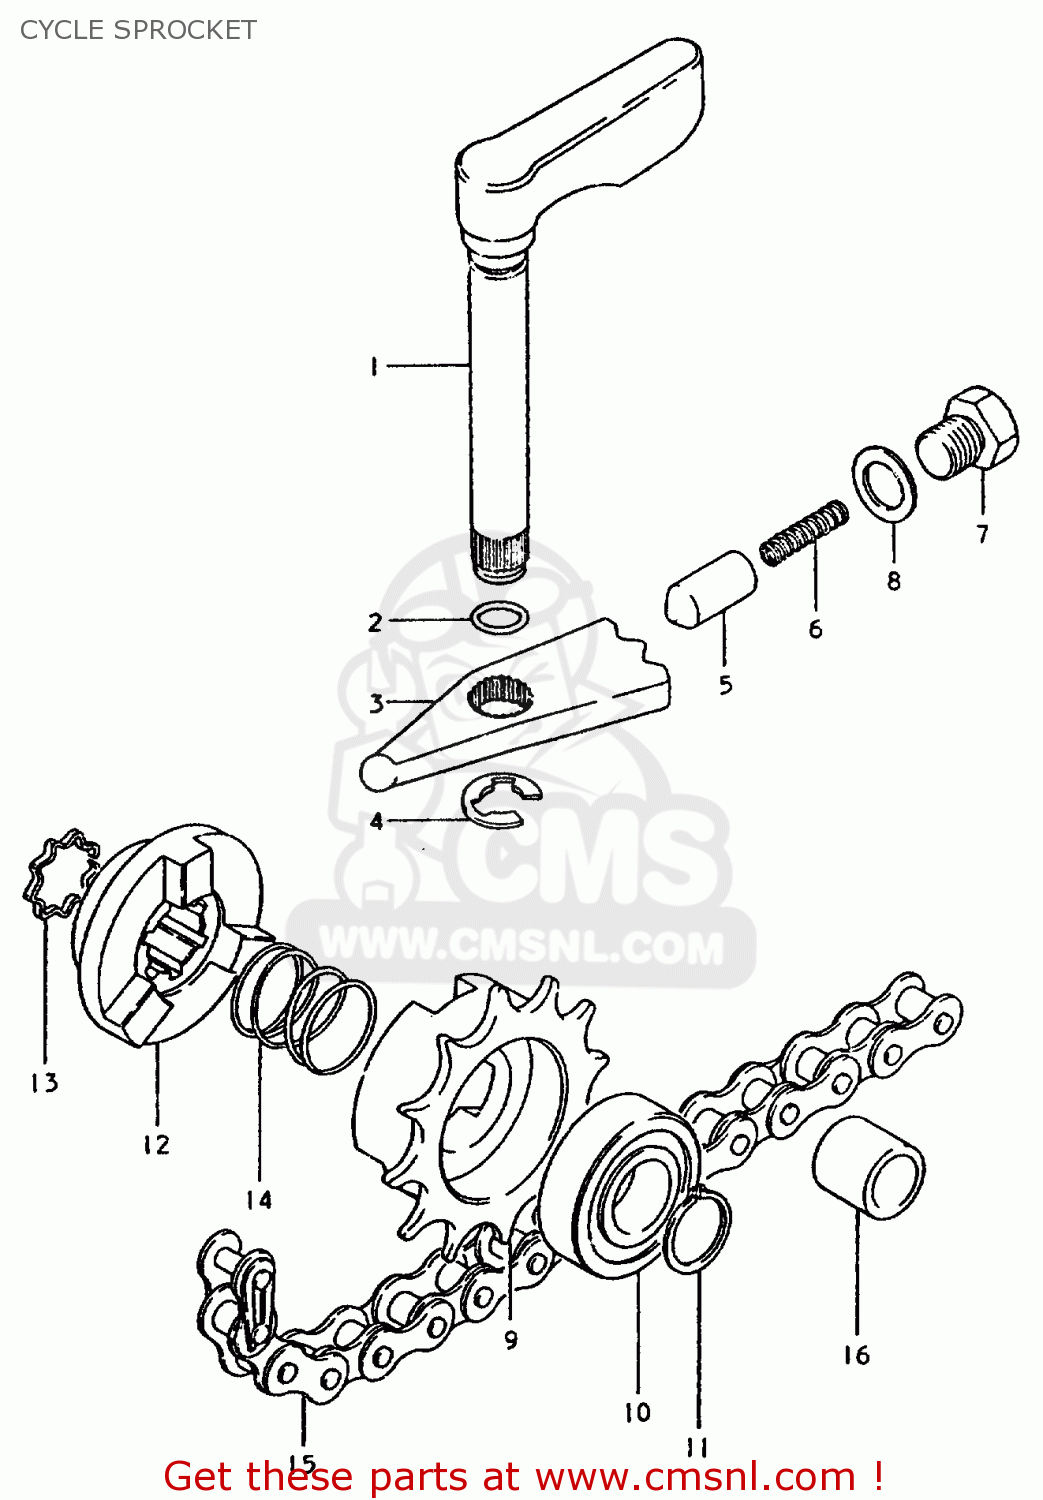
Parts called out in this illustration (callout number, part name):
1	LEVER, SPROCKET SHIFTING
2	O RING(D:1.3,ID:7.6)
3	ARM, SPROCKET SHIFTING
4	E RING
5	STOPPER
6	SPRING
7	BOLT 10X9
8	WASHER
9	SPROCKET, CYCLE (NT:12)
10	BEARING
11	CIRCLIP,15MM
12	WHEEL
13	RING,ENGINE SPROCKET
14	SPRING
15	CHAIN, CYCLE (48L)
16	HOSE
